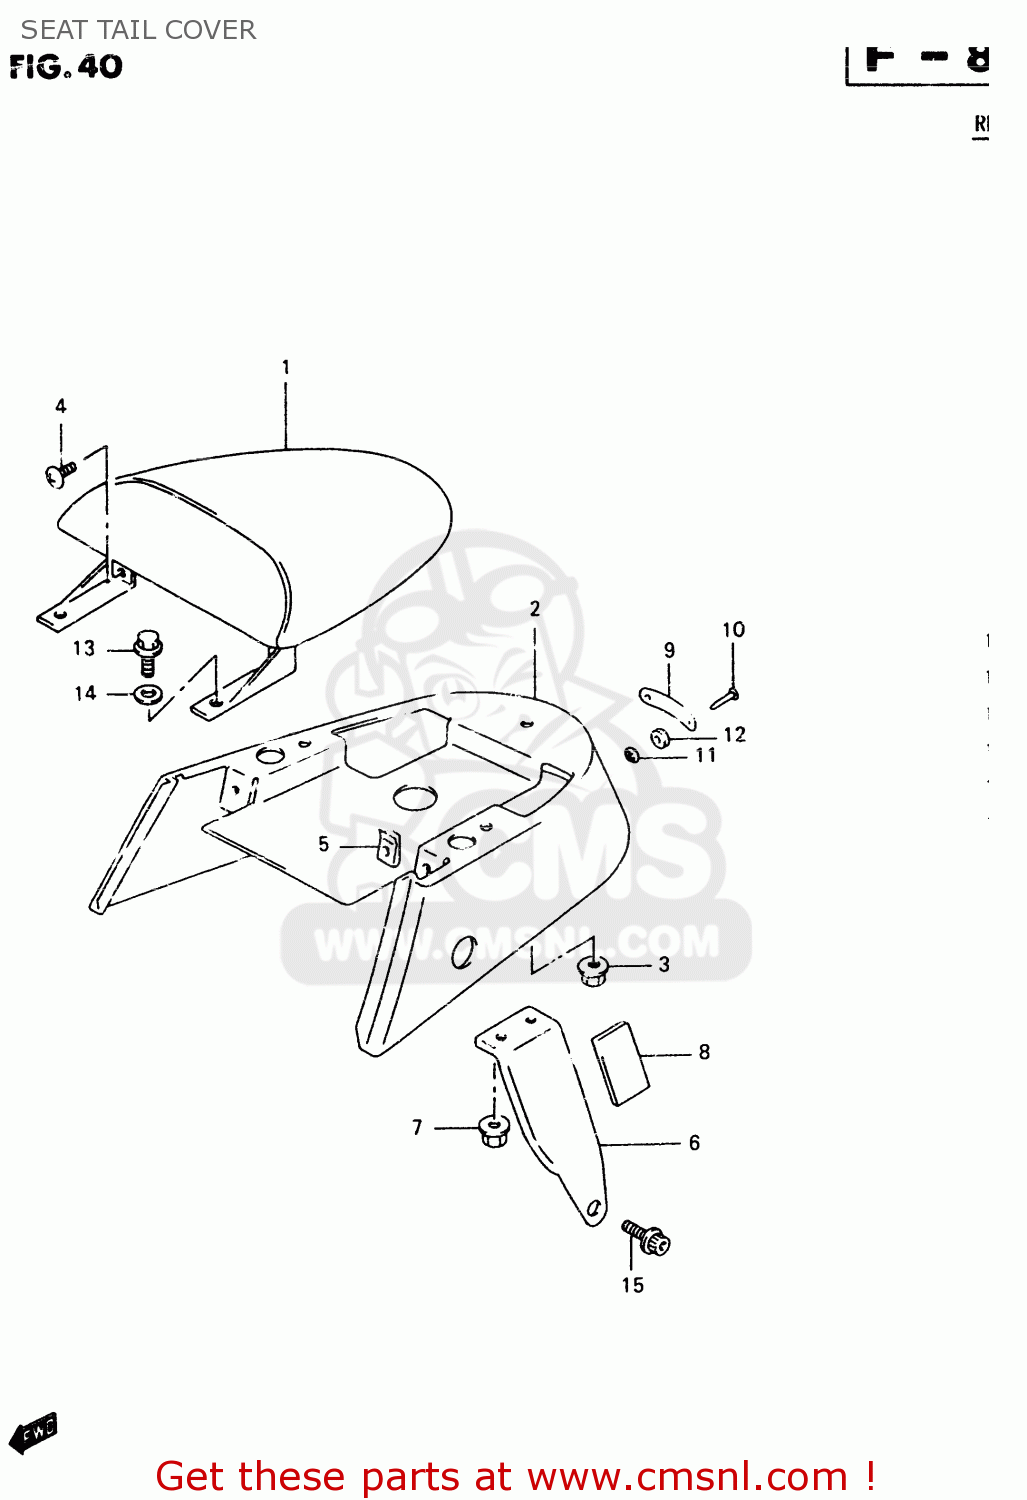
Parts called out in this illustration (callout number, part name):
1	SEAT ASSY,PILLION
2	COVER,SEAT TAIL
3	NUT
4	SCREW,3X20
5	NUT
6	BRACKET,PILLION SEAT,R
7	NUT
8	CUSHION(30X60X10)
9	PLATE,TAIL COVER
10	RIVET
11	NUT
12	CUSHION(15X15)
13	BOLT
14	WASHER
15	PLUG
